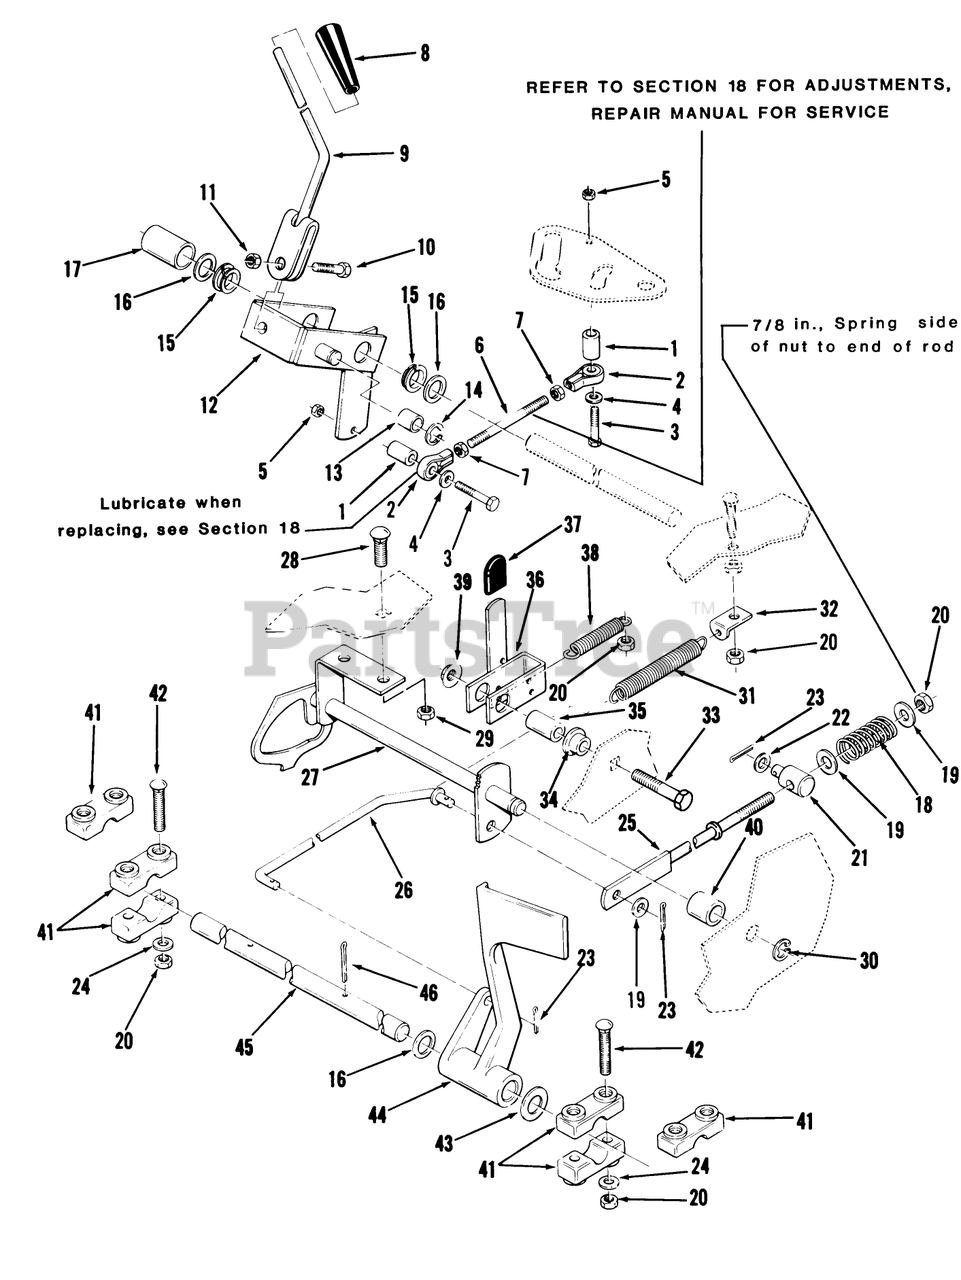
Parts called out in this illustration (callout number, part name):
1	BEARING CAM ROLLER
2	ASSY ROD END
8	KNOB
13	BEARING-CAM RETURN
21	TRUNNION-LIFT
24	WASHER 5/16 SAE
32	CLIP - SPRING
34	SPACER
35	SPACER
37	GRIP
38	SPRING-EXTENSION
43	Special Washer
44	PEDAL CLUTCH *R
